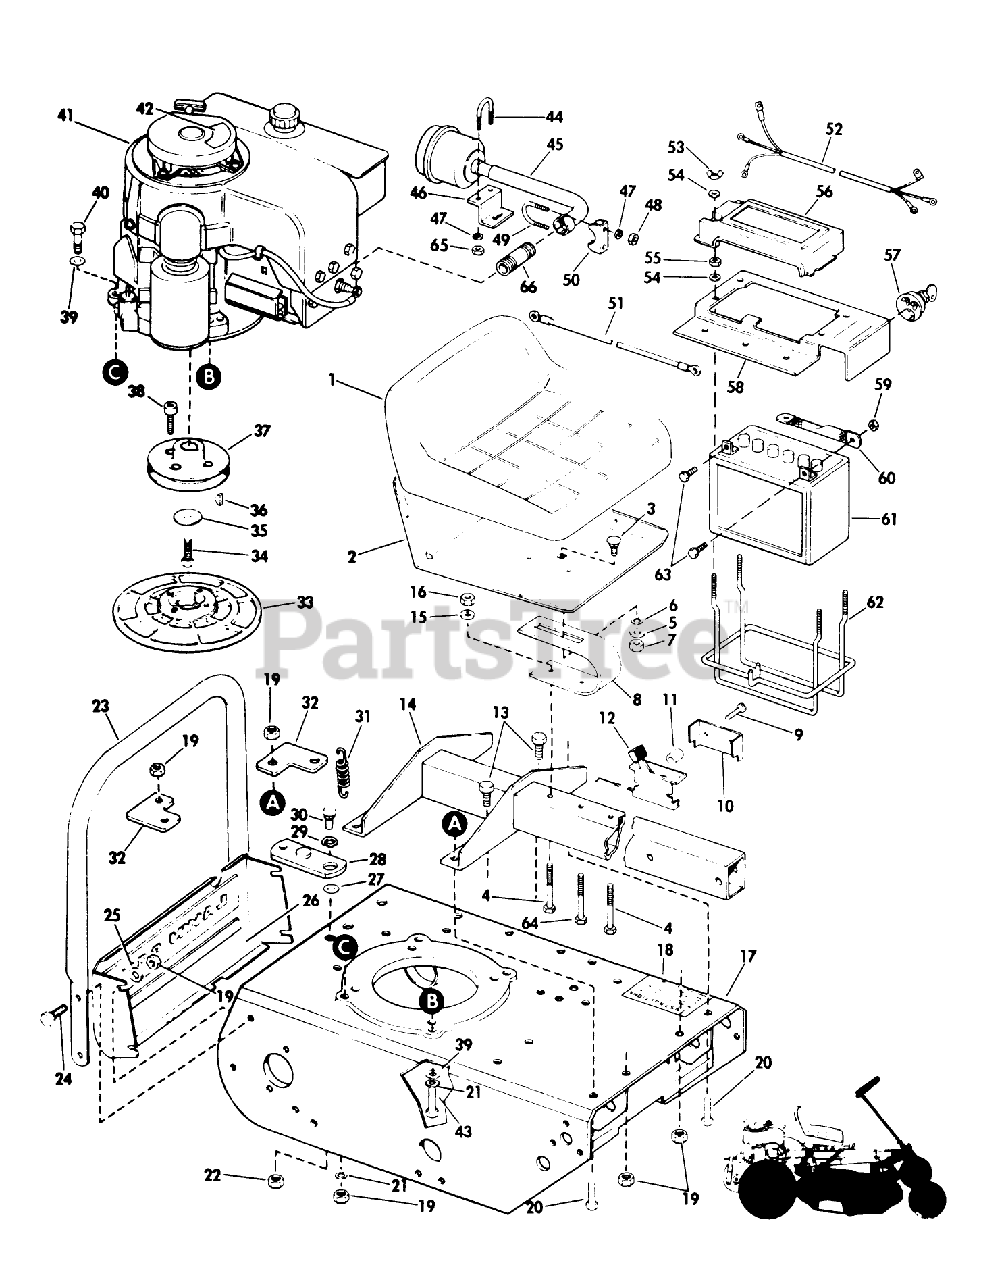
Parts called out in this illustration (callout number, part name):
12	Throttle Control Assembly
42	Decal-Caution
55	STOP NUT
